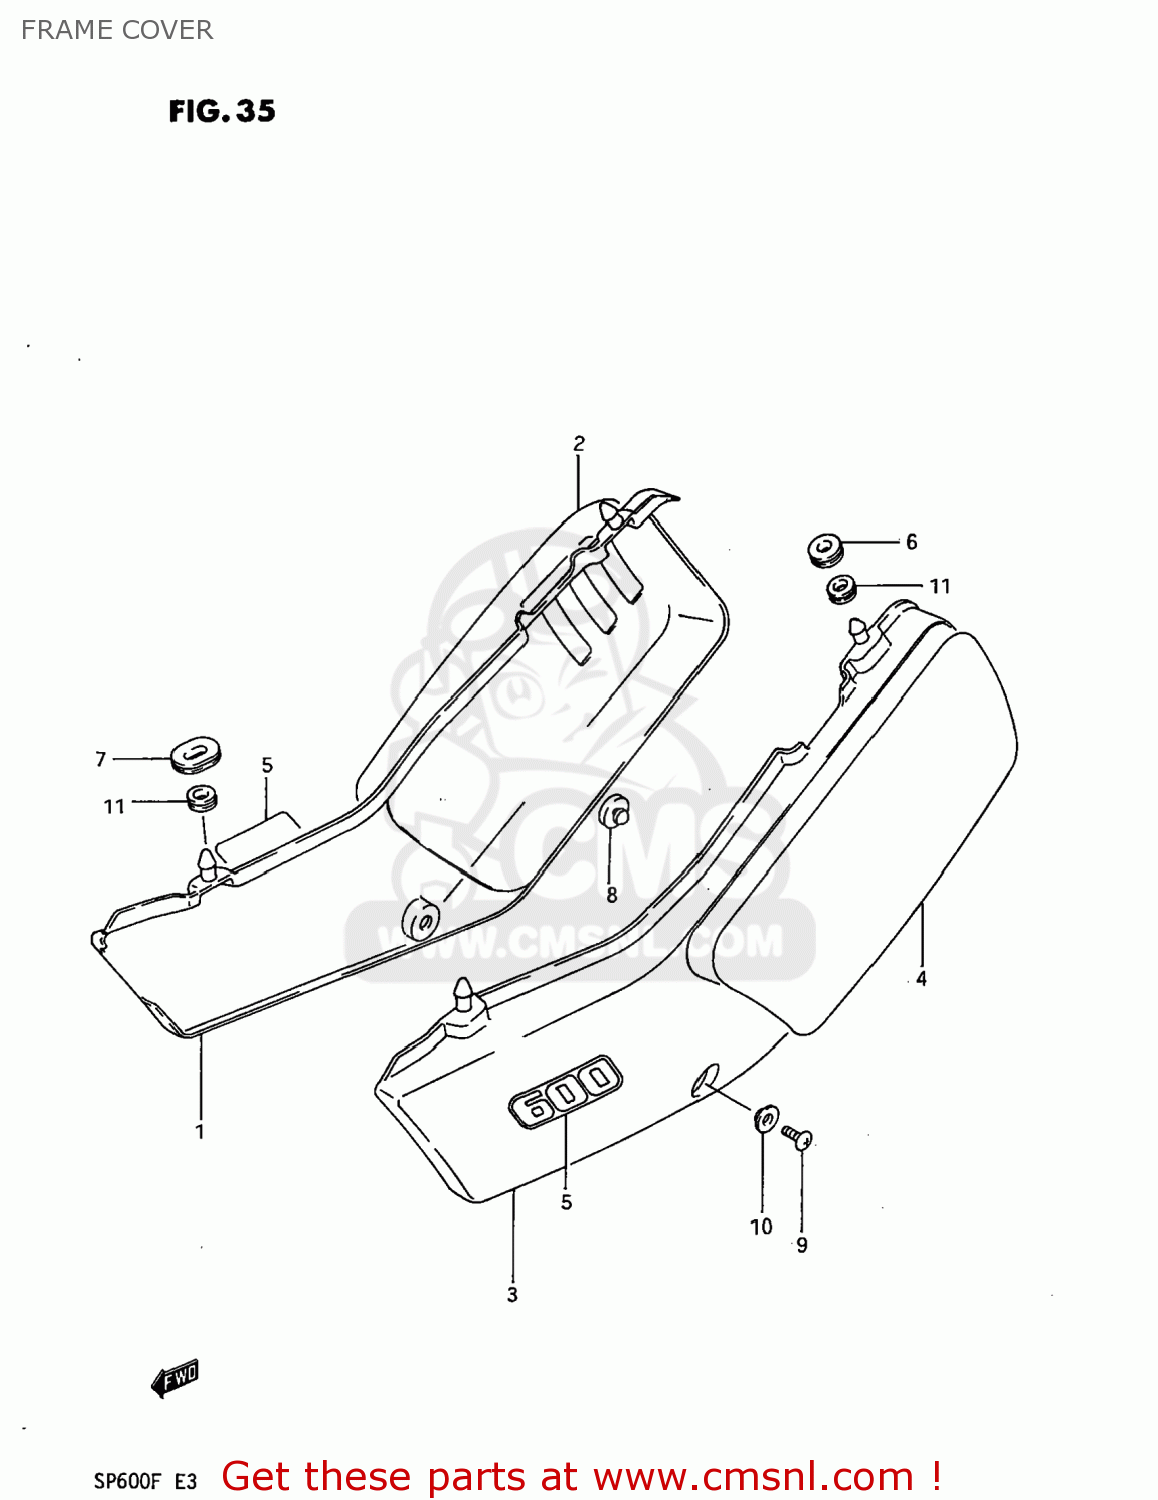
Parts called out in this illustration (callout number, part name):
1	COVER,FRAME,RIGHT
2	EMBLEM,FRAME COVER NUMBER
3	COVER,FRAME,LEFT
4	EMBLEM,FRAME COVER NUMBER
5	EMBLEM,FRAME COVER
6	CUSHION
7	CUSHION
8	CUSHION
9	SCREW 6X12
10	WASHER
11	CUSHION,SIDE COVER BOSS
